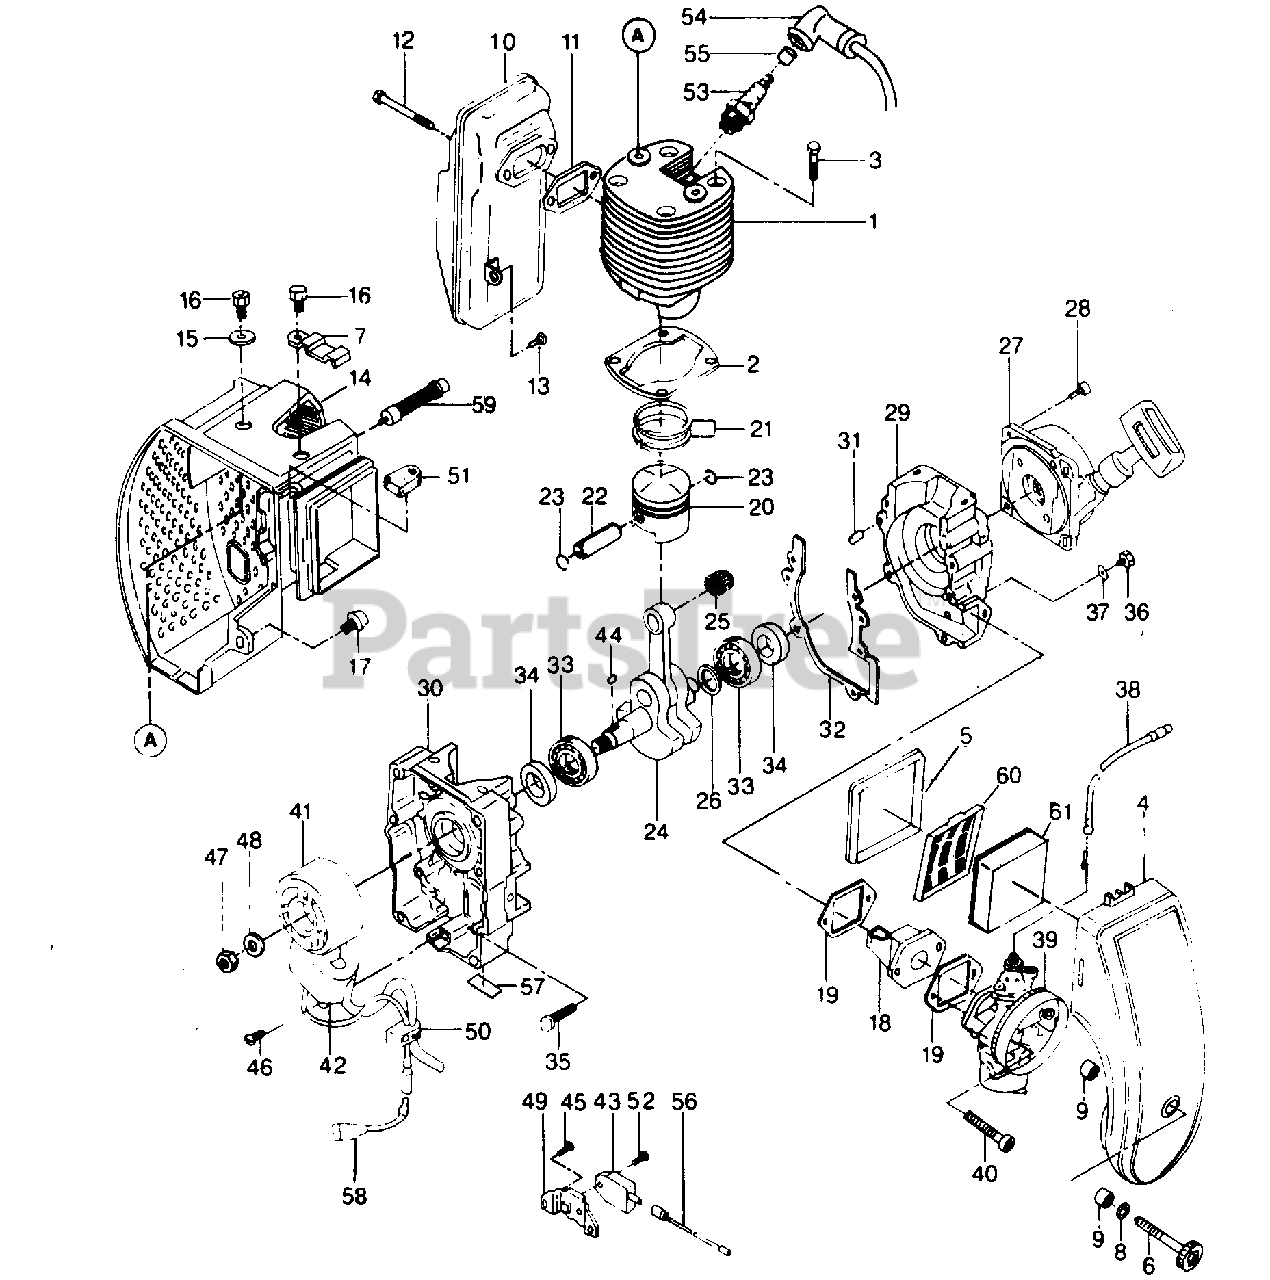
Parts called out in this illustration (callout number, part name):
1	Cylinder
4	Air Cleaner Ass'y.
8	O - Ring
10	Muffler Ass'y.
13	Screw (6 x 14mm)
14	Cover - Cylinder
18	Reed Valve Ass'y.
21	Piston Ring Set
22	Pin - Piston
23	Ring - Snap
24	Crank Shaft Ass'y.
25	Bearing - Needle
26	Shim (obsolete)
27	Recoil Starter Ass'y.
28	Screw (4 x 16mm)
29	Crankcase
30	Crankcase
31	Pin - Dowel
33	Bearing - Ball
34	Seal - Oil
35	Screw (6 x 30mm)
36	Bolt (6 x 8mm)
39	Carburetor Ass'y.
40	Screw (6 x 45mm)
41	Flywheel
42	Coil - Ignition
45	Screw (5 x 8mm)
46	Screw (5 x 20mm)
47	Nut (10mm)
52	Screw (4 x 6mm)
53	Plug - Spark (NGK B75) (outside vendor)
54	Boot - Spark Plug
55	Connector
56	Wire - Lead
58	Wire Connector (outside vendor)
59	Spark Arrestor Ignition
60	Air Filter
61	Retainer (outside vendor)
